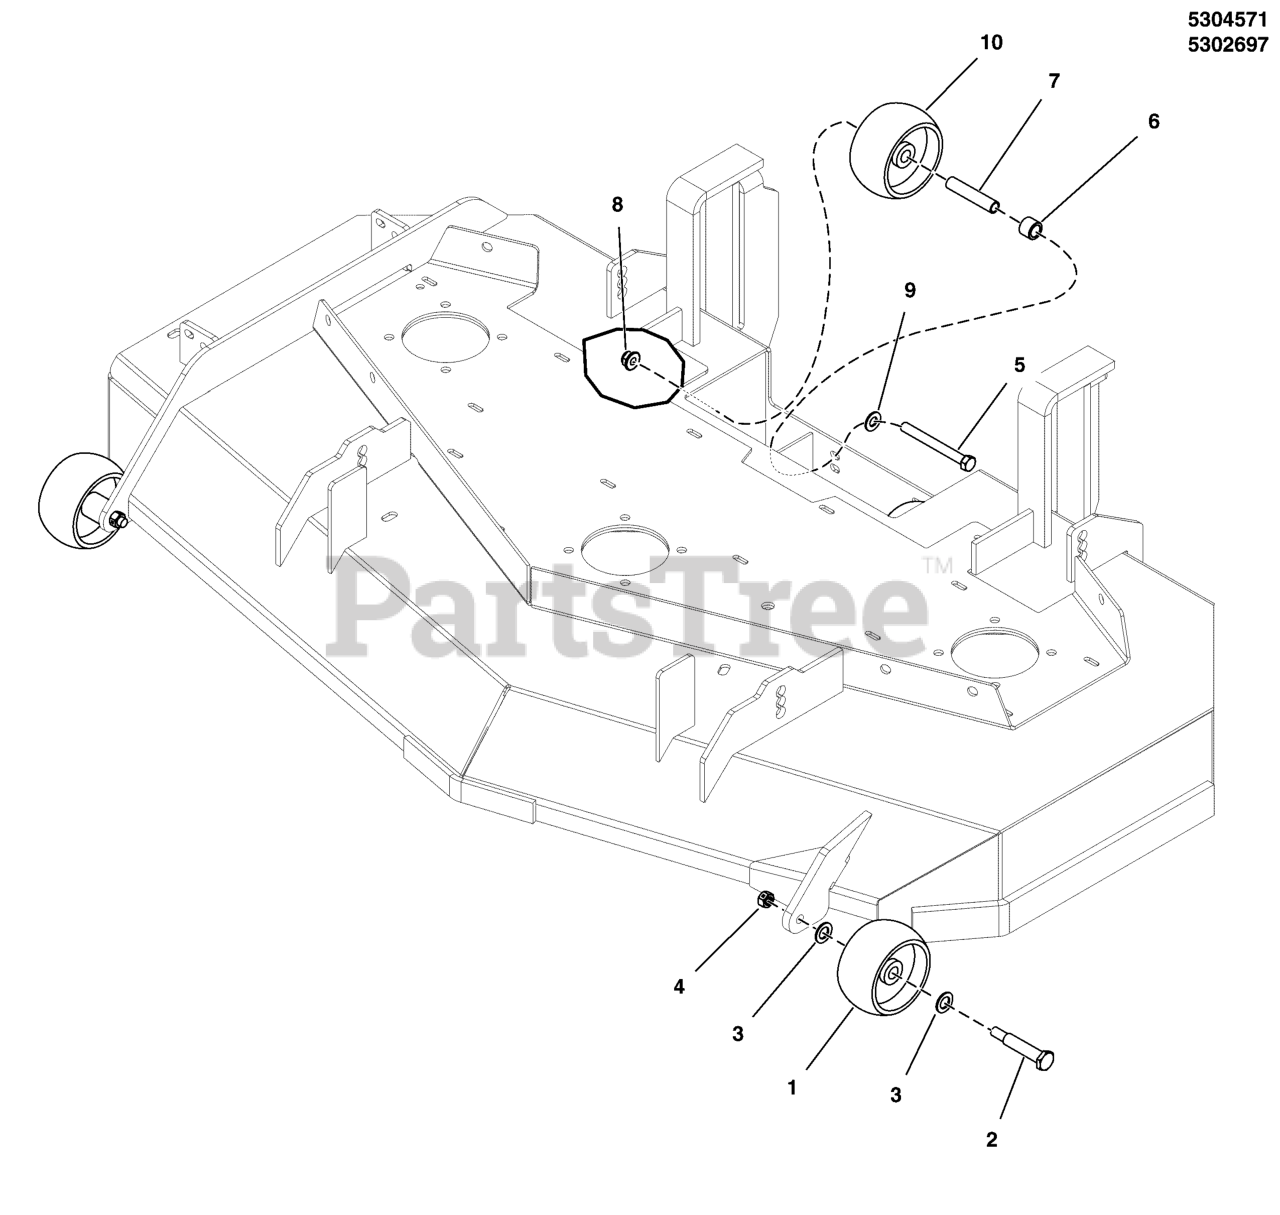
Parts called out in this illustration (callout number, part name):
1	WHEEL- 2.00 WIDE 3.88 DIA 0.531ID POLY
2	BOLT-WHEEL 3/8-16X2.781 .750 THRD
3	WASHER,.516IDX.875ODX.06,FLAT,ZC/CL
4	NUT, 3/8-16 HEX SIDE LOCK
5	BOLT, 3/8-16 X 3-1/2" GD5 CZ
6	SPACER, .51 X .75 X .56, PM, CZ
7	SPACER, .38 X .50 X 2.50, CZ
8	NUT, 3/8-16 HEX NYLOCK FLANGE
9	WASHER, 3/8 SAE
10	WHEEL- 2.00 WIDE 3.88 DIA 0.531ID POLY
